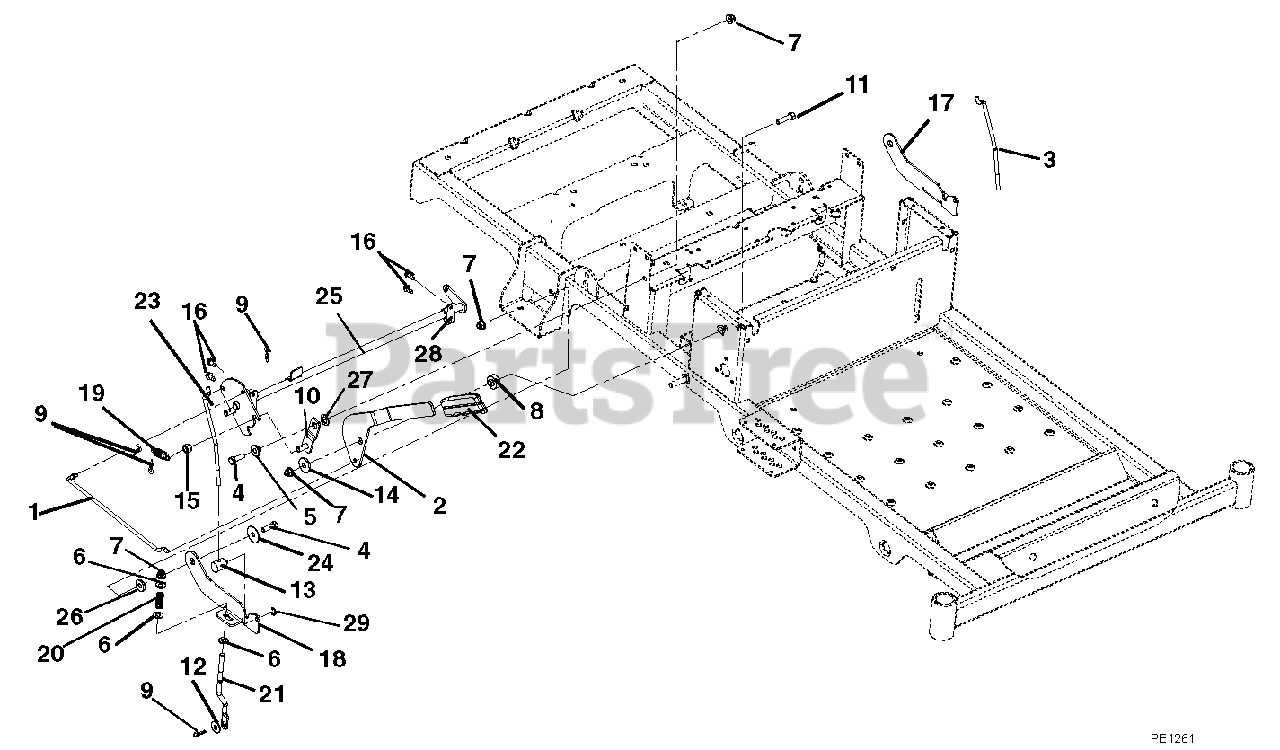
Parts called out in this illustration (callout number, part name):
1	Link, Brake Handle
2	Handle, Parking Brake
3	Link, Neutral LH
4	Bolt, Hex .31-18 x 1.00 Grade 5
5	Bushing, Flange .312 x .500 x .344 x .880
6	Washer, Flat-Steel .344 x .688 x .065
7	Nut, Flange Nyloc 5/16-18
8	Spacer, Brake Handle
9	Pin, Hair Internal .08 x .18 x 1.18
10	Weldment, Detent Arm
11	Bolt, Hex .31-18 x 1.25 Grade 5
12	Washer, Flat Steel .38 x .875 x .083
13	Trunnion, 1/4-20
14	Washer, Flat Steel .344 x 1.125 x .135
16	Screw, Tapping .25-20 x .50 Hex Washer Head
17	Latch, LH Neutral
18	Latch, RH Neutral
19	Spring, Tension .072 x .565 x 1.87
20	Spring, Compression
21	Link, Brake Cog
22	Grip, Park Brake
23	Link, Neutral RH
24	Washer, Flat Steel .347 x 1.254 x .048
25	Weldment, Brake Shaft
26	Bushing, Flange .325 x .499 x .26 x .88
27	Washer, Flat-Steel .52 x .827x .062
28	Bushing, .50 Clamp Block Molded
29	Ring, Retaining-External .250 x .025
